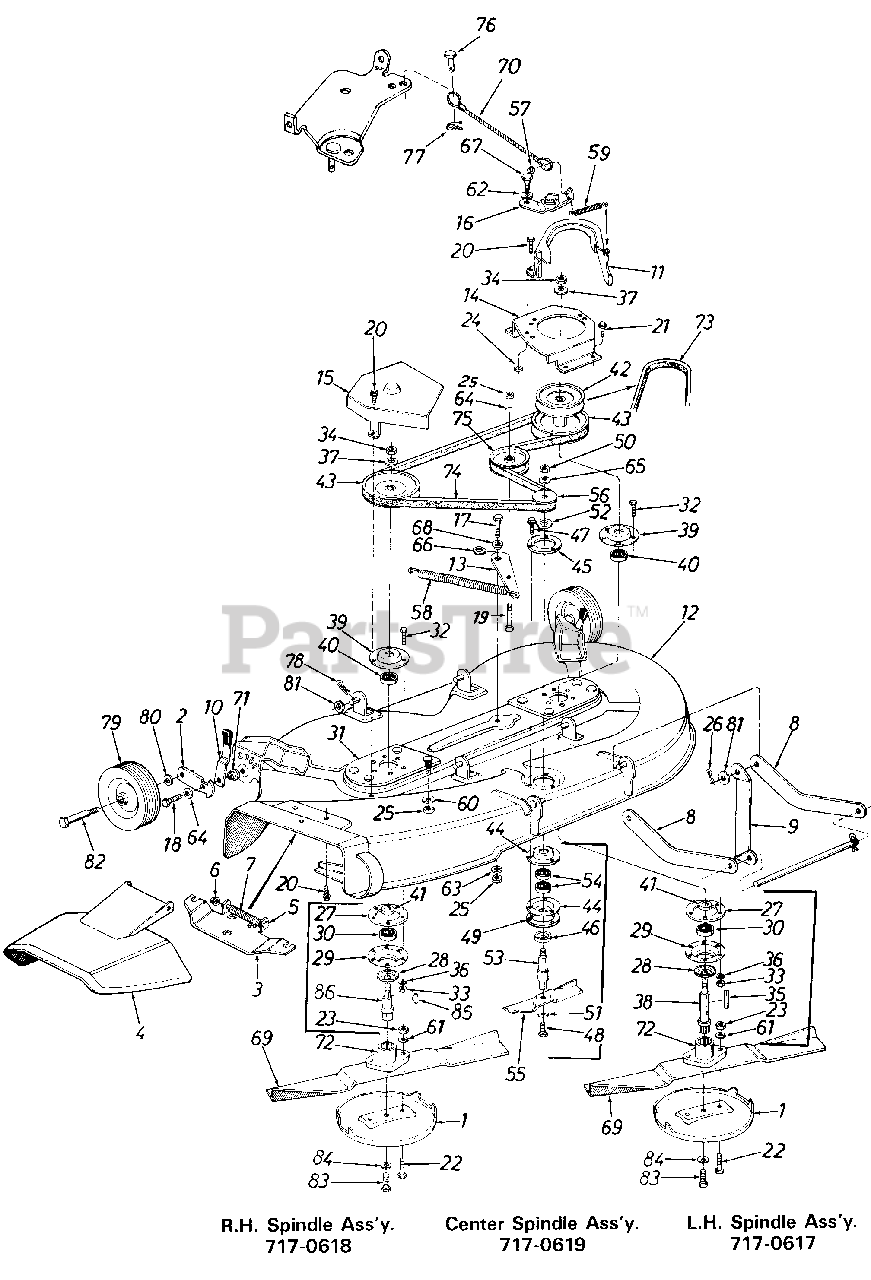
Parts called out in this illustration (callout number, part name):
1	Anti-Scalp Plate
2	Wheel Pivot Bar
3	Adapter
4	Chute CoverAss'y.
5	Hinge Pin
6	Cap Speed Nut 1/4" Rod.
7	Torsion Spring
11	Belt Guard
12	44" DeckAssy.
13	Idler Bracket
14	Pulley Cover-L.H.
17	Hex Bolt 3/8-24 x 1.00"
18	Hex Bolt 3/8-24 x 1.25" Lg.
19	Hex Bolt 3/8-24 x 1.50"
20	Hex Wash. S-Tapp Scr. 1/4-20 x .50"
21	Hex Wash. Hd. Tapp Scr. 5/16-18 x .75" Lg.
22	Hex Bolt 5/16-24x 1.25" (Grade 5)
23	Hex Nut 5/16-24 Thd.
24	Hex Cent. L.-Nut 5/16-18 Thd.
25	Hex Nut 3/8-24 Thd.
26	Cotter Pin 3/32 Dia. x 1.00" Lg.
27	Reinforcement Plate
28	Bearing Shield
29	Open Brg. Housing 1.85 I.D.
30	Ball Brg. .787 I.D. x 1.85 O.D. x .551
31	Spindle Mounting Plate Ass'y.
32	Hex Bolt 5/16-24 x 1.0" Lg.
33	Hex Nut-5/16-24
34	Hex Jam Nut 5/8-18 Thd.
35	Square Key 3/16 x 2.25" Lg.
36	L-Wash . 5/ 16 I.D.
37	Bell. Wash. .630 I.D. x 1.25 x .090
38	44" Deck Blade Spindle
39	Bearing Housing 1.85 I.D.
40	Ball. Brg. .787 I.D. x 1.85 O.D. x .551
41	Spacer 1.0 O.D. x .790 I.D. x .350 Lg.
42	5/8 "V"-Pulley .79 I.D. x 5.75 O.D.
43	"V"-Pulley .79 I.D. x 6.50 O.D.
44	1-3/8" I.D.-Bearing Housinc
45	Reinforcement Plate
46	Bearing Shield
47	Hex "B" Tap Scr. .250x .750 Lg.
48	Hex Cl.-Scr. 3/8-24 x .88 Lg.
49	Reinforcement Plate
50	Hex Jam Nut 1/2-20Thd.
51	Bell.-Wash. .400 I.D. x .88 O.D. x .060
52	Fl.-Wash. .635 x 1.04 O.D. x . 1 20"
53	6.5" Blade Spindle
54	Ball Brg. .62 I.D. x 1.30" O.D. x .44 "
55	6.50" Blade
56	1/2" V-Pulley Half .625 I.D. x 2.25" O.D.
57	Cap Speed Nut 1/4" Rod.
58	Extension Spring .73 O.D. x 431 Lg.
59	Extension Spring .38 x 2.75" Lg.
60	Bell.-Wash. .400 I.D. x .88 O.D. x .060
61	L.-Wash. 5/16" I.D.
62	Spri ng Wash . .445 I.D. x .75 O.D. x .017
64	Bell.-Wash. .400 I.D. x 1.13 O.D. x .030
65	Bell.-Wash. .505 I.D. x 1.00 O.D. x .075
66	Spring Wash. .650 I.D. x .875 O.D. x .015 Thk.
67	Shld. Bolt .437 Dia. x .180
68	Shld. Spacer.625 I.D.
69	Mower Blade 21.88
70	Brake Cable Ass'y.
71	Shld. Spacer
72	Blade Adapter
73	"V"-Belt 1/2 x 56" Lg.
74	"V"-Belt 1/2 x 74"Lg.
75	Fl.-Idler w/Flanges 3.50 O.D.
76	ClevisPin 1/4 Dia. x .53 Lg.
77	Intern. Cotter Pin 5/16" Dia.
78	Intern. Cotter Pin 1/2" Dia.
79	Deck Wheel 6.0 x 1.38
80	BelI .-Wash. .400 I.D. x .88 O.D. x .060
81	Fl.-Wash. .531 I.D. x .93 O.D. x .090
82	Shoulder Bolt 3/8-16 x 1.41
83	Hex Bolt 3/8-24 x .88" Lg.
84	L.-Washer 3/8 I.D.
85	Sq. Key 3/16 x .75" Lg.
86	44" Deck Blade Spindle
